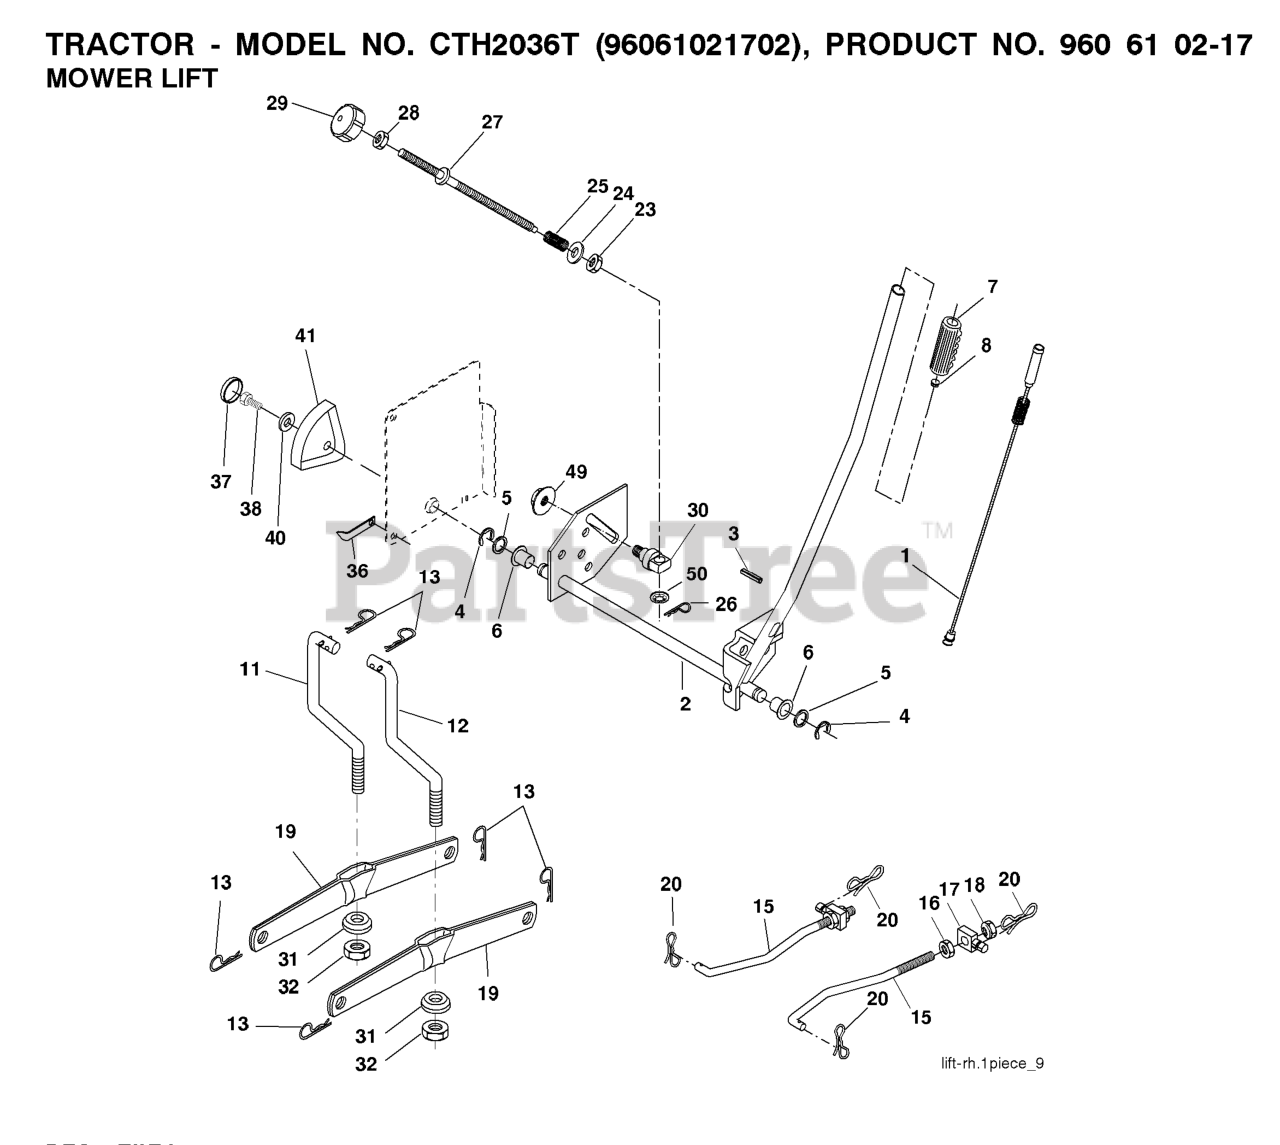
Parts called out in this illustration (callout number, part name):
1	PLUNGER.ASM.LIFT.LEVER.BLK.
2	SHAFT.ASM.LIFT.YT
3	PIN.GROOVE.5/16
4	RETAINING RING LT
6	BEARING.NYLON
7	GRIP HANDLE
8	PLUNGER BUT KIT
11	LINK
12	LINK
13	RETAINER-SPRNG RB
15	LINK.SUSPENSION.FRONT
16	NUT.HEX.JAM.1/2-13
18	NUT.LK.W/WSH.1/2.
19	ARM.REAR.SUSPENSION
20	PIN.COTTER.7/16.BOW TI.
26	RETAINER CLIP
27	ROD ADJ LIFT
28	NUT
29	KNOB INF 3/8-16
31	BEARING.PIVOT.LIFT
32	NUT CROWNLOCK 3/8-24
36	POINTER, HEIGHT INDICATOR(2 2)
38	SCREW 5/16-18X1
41	HEIGHT INDICATOR
49	NUT
50	NUT PUSH M
